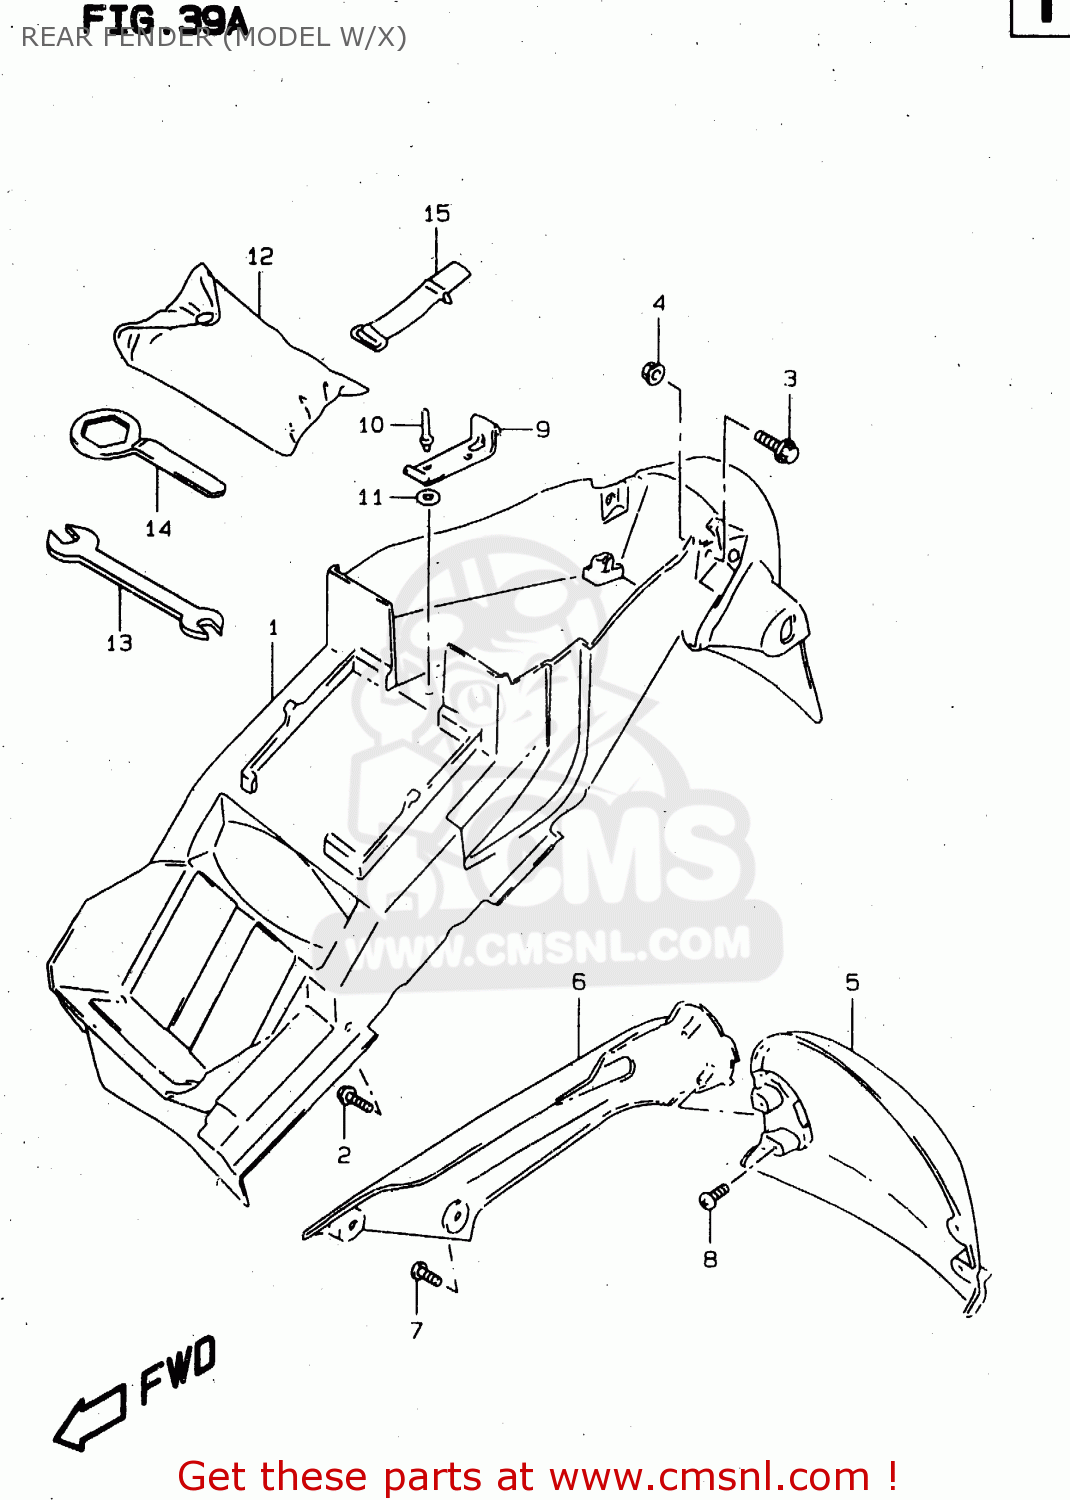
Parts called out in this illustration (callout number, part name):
1	FENDER,RR
2	BOLT 6X16.5
3	BOLT 6X16
4	NUT
5	FENDER,RR LOW CTR
6	FENDER,RR LOW,R
7	SCREW (6X14)
8	SCREW
9	HOLDER,TOOL
10	RIVET
11	WASHER
12	TOOL ASSY
13	OPEN SPANNER(8X10)
14	RING SPANNER(36)
15	BAND,TOOL
